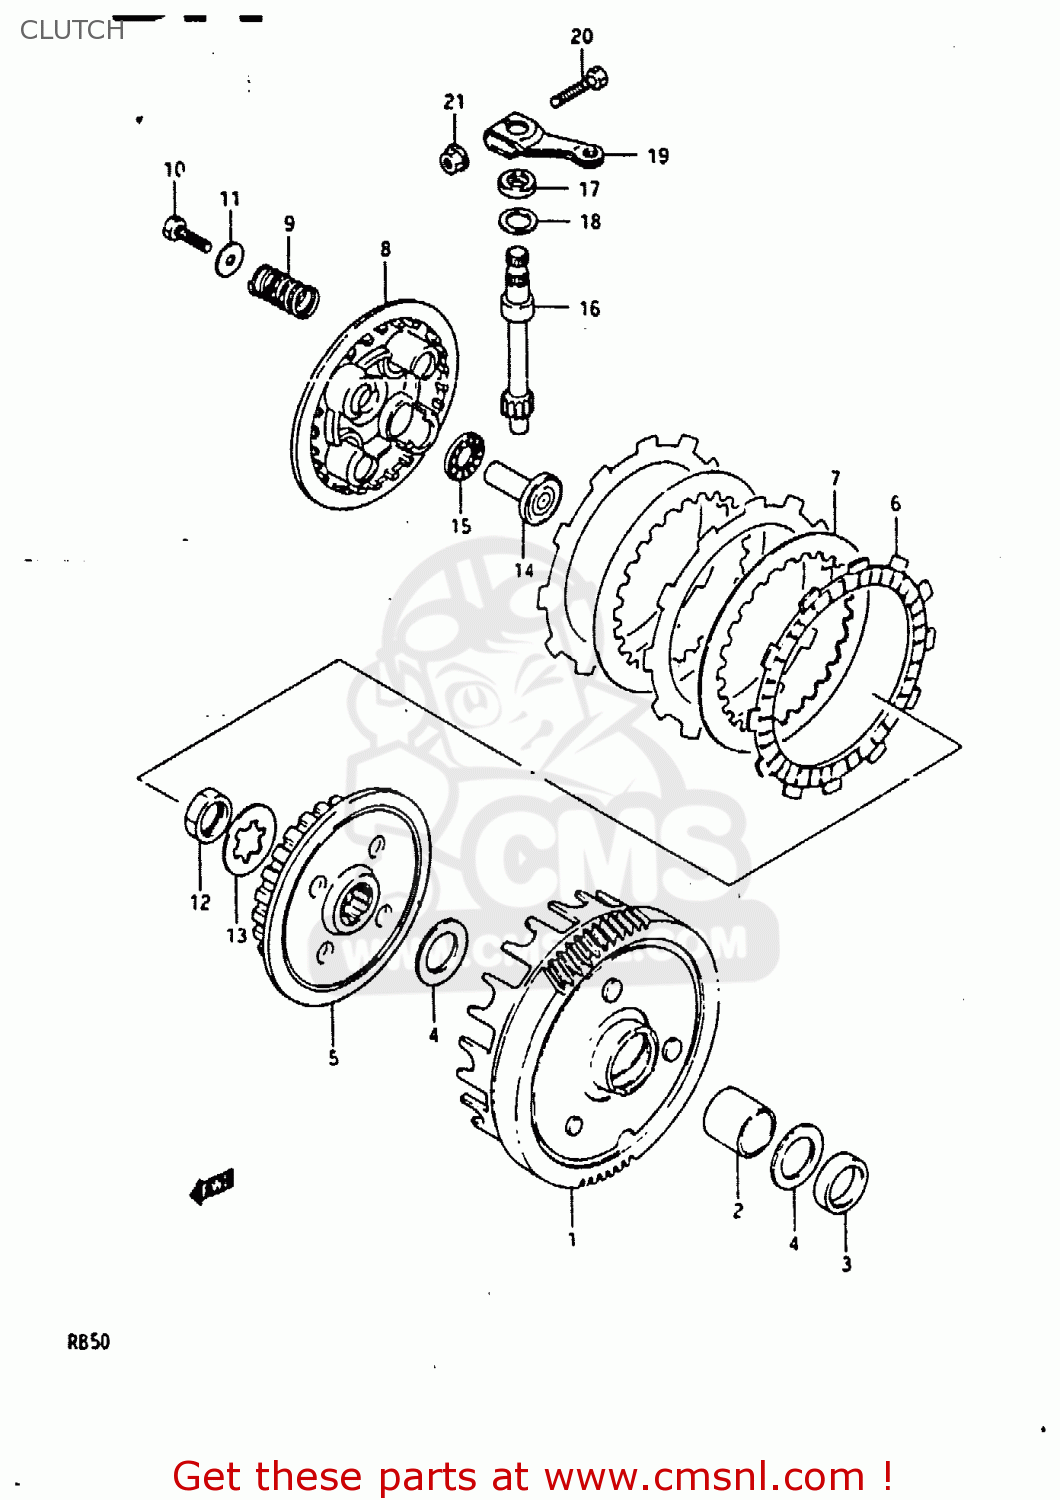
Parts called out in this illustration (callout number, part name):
1	GEAR ASSY,PRI DRIVEN
2	SPACER (17X22X21)
3	SPACER(17X24X7)
4	WASHER
5	HUB,CLUTCH SLEEVE
6	PLATE,CLUTCH DRIVE (MCA)
7	PLATE,CLUTCH DRIVEN (NAS)
8	DISC,CLUTCH PRESSURE
9	SPRING
10	BOLT(5X16)
11	WASHER (5.5X16X1.2)
12	NUT
13	WASHER,LOCK
14	RACK,CLUTCH RELEASE
15	BEARING(10X22X2.8)
16	PINION,CLUTCH RELEASE
17	OIL SEAL
18	WASHER (12X17X1)
19	ARM,CLUTCH RELEASE
20	BOLT
21	NUT 6MM
